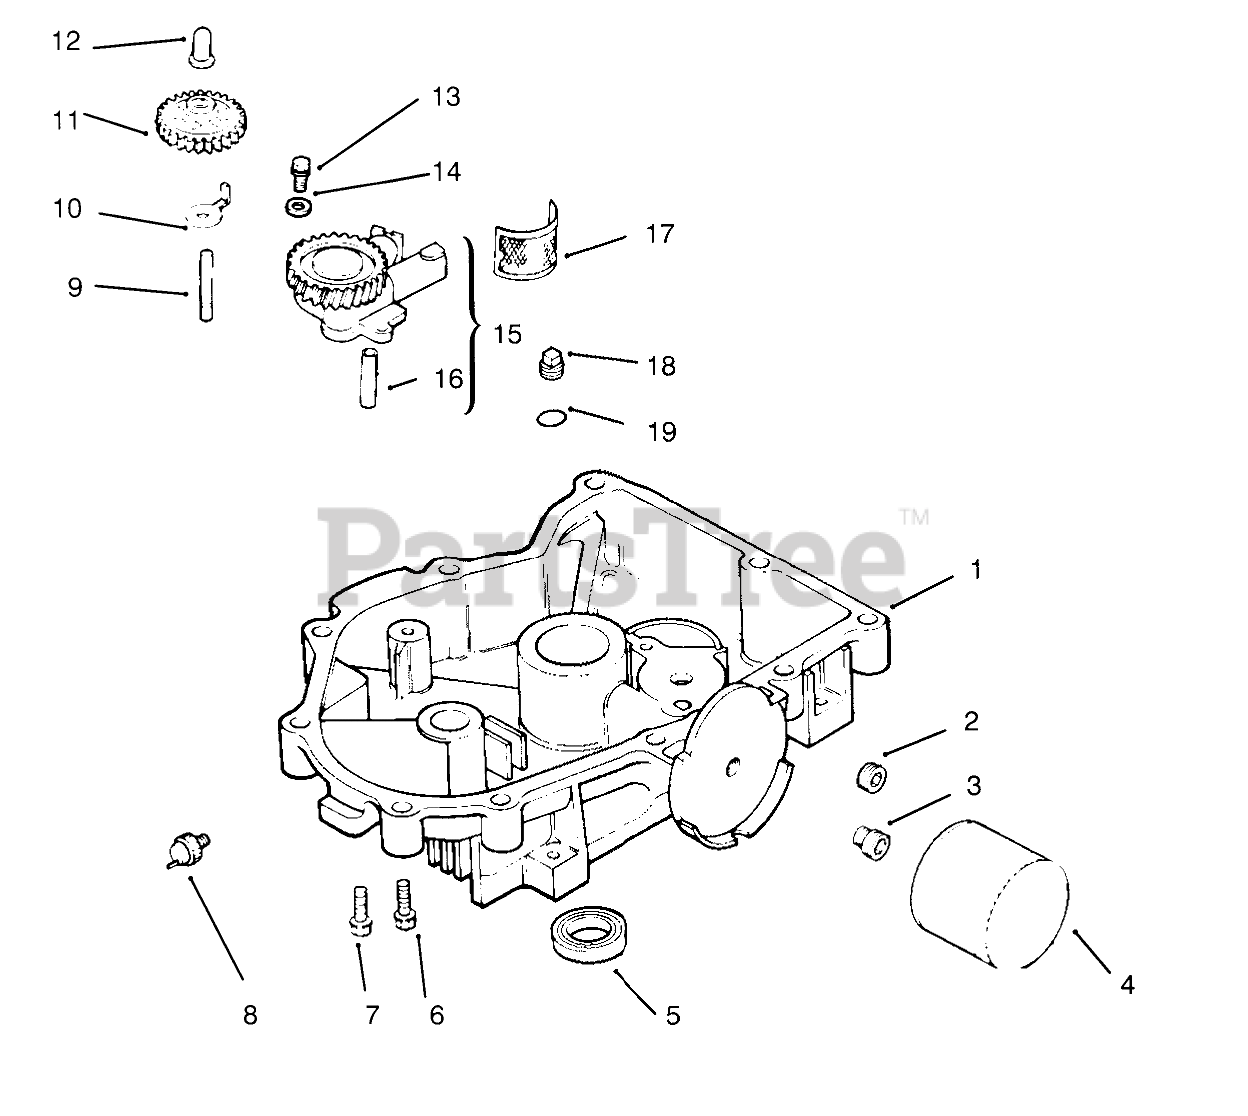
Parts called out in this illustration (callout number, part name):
1	Oil Pan
2	Plug-Hex
3	Nipple-Filter, Oil
4	Filter-Oil
5	Seal-Oil
6	Screw
7	Screw
8	Switch, pressure
9	Shaft-Gear, Governor
10	Tab-Locking
11	Governor Gear ASM
12	Pin-Governor
13	Screw
15	Oil Pump ASM INC 16
16	Tube-Oil Pickup
17	Screen-Oil Pickup
18	Plug
19	O Ring
